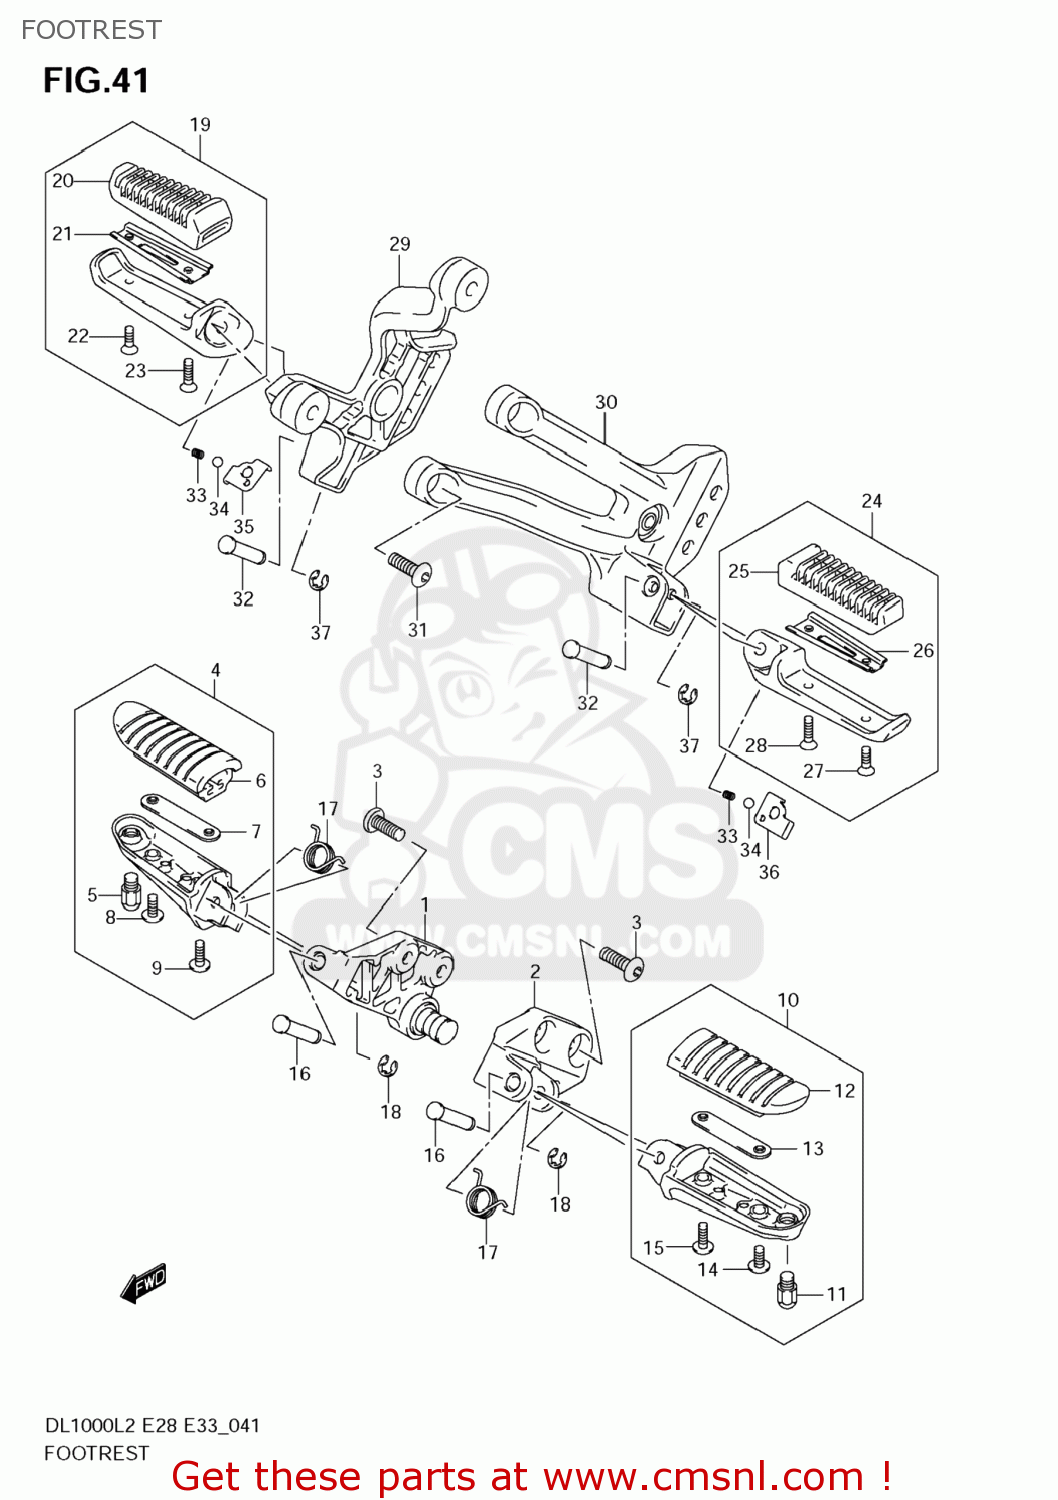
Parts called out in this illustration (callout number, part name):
1	BRACKET,FR FOOTREST,R
2	BRACKET,FR FOOTREST,L
3	BOLT(8X23)
4	FOOTREST ASSY,FR,R
5	BOLT,BANK SENSOR
6	RUBBER,FOOTREST
7	PLATE,FR FOOTREST RUBBER
8	SCREW
9	SCREW
10	FOOTREST ASSY,FR,L
11	BOLT,BANK SENSOR
12	RUBBER,FOOTREST
13	PLATE,FR FOOTREST RUBBER
14	SCREW
15	SCREW
16	PIN
17	SPRING
18	E RING
19	FOOTREST ASSY,PILLION,R
20	RUBBER,RR FOOTREST
21	PLATE,RUBBER STOPPER
22	SCREW
23	SCREW
24	FOOTREST ASSY,PILLION,L
25	RUBBER,RR FOOTREST
26	PLATE,RUBBER STOPPER
27	SCREW
28	SCREW
29	BRACKET,PILLION FOOT,R(BLACK)
30	BRACKET,PILLION FOOT,L(BLACK)
31	BOLT(8X23)
32	PIN(8X33.2)
33	SPRING
34	BALL
35	PLATE,PILLION FOOTREST,R
36	PLATE,PILLION FOOTREST,L
37	E RING
